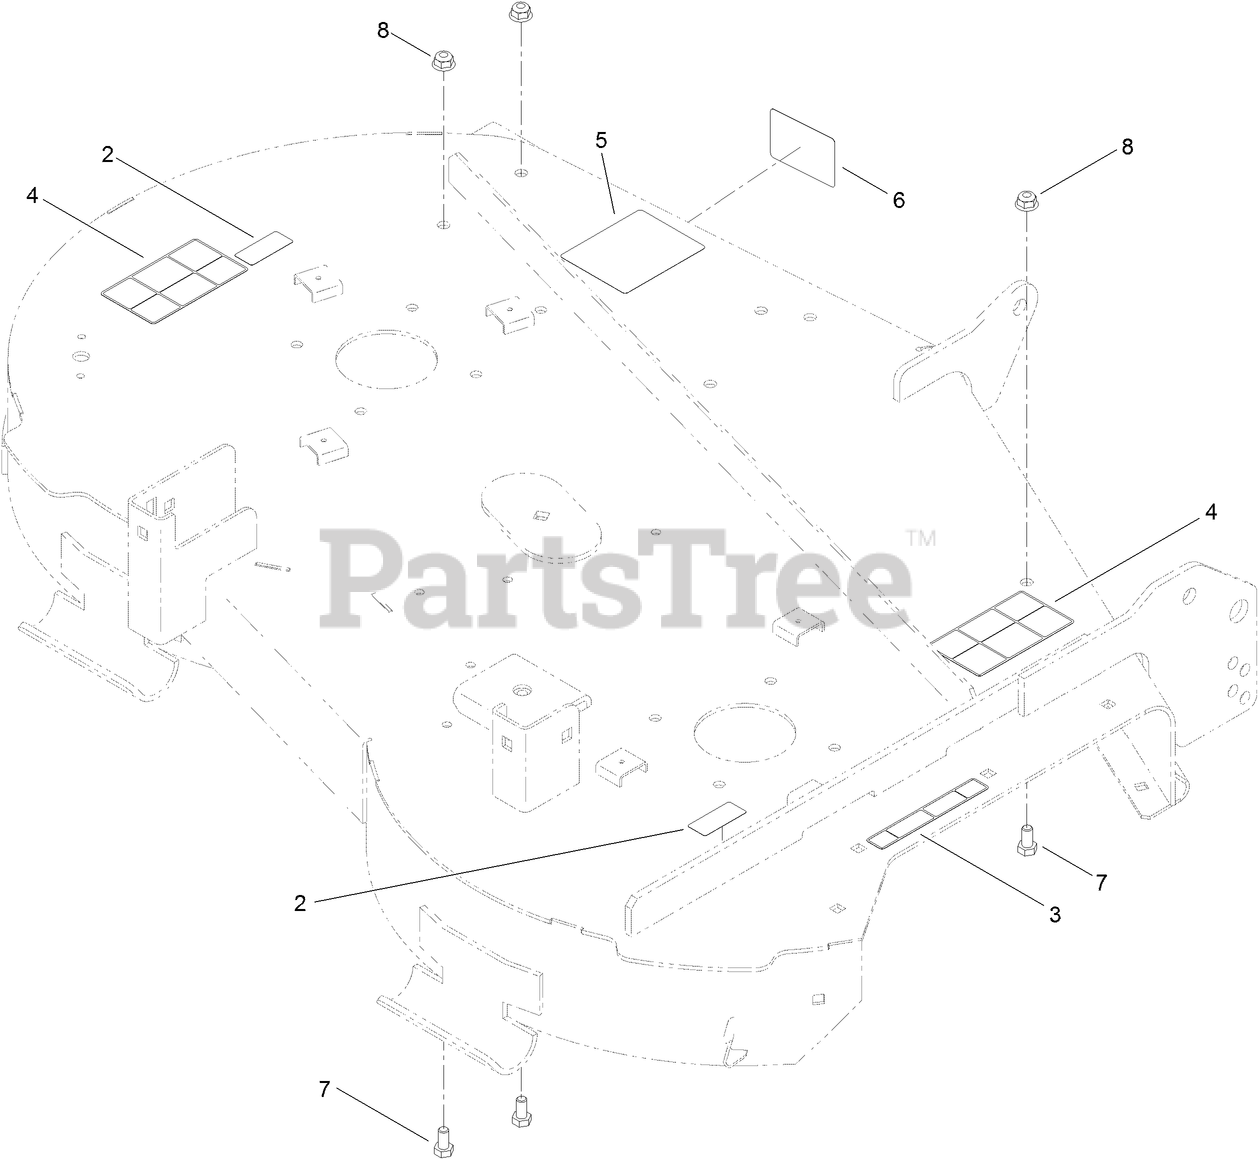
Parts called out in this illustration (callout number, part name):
2	DECAL-DANGER
3	DECAL-DANGER
4	DECAL-DANGER
5	DECAL-ROUTING, BELT
6	DECAL-SCALP, ANTI
7	SCREW-HH
8	NUT-HF, NI
